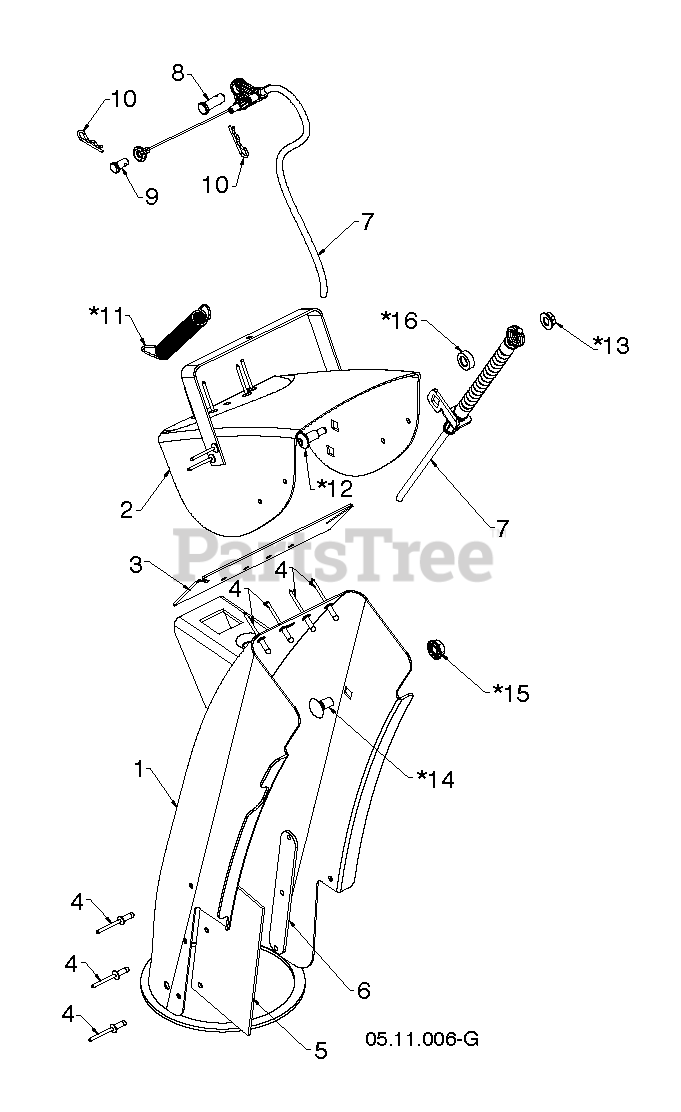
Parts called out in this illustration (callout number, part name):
1	ASM.CHUTE/DEFLECTOR.428
7	CABLE.CONTROL.CHUTE.DEFLEC
8	PIN CLEVIS 5/16X.875
9	PIN CLEVIS .25 X .31
10	HAIRPIN.SOFT.ZINC.059X1.125
